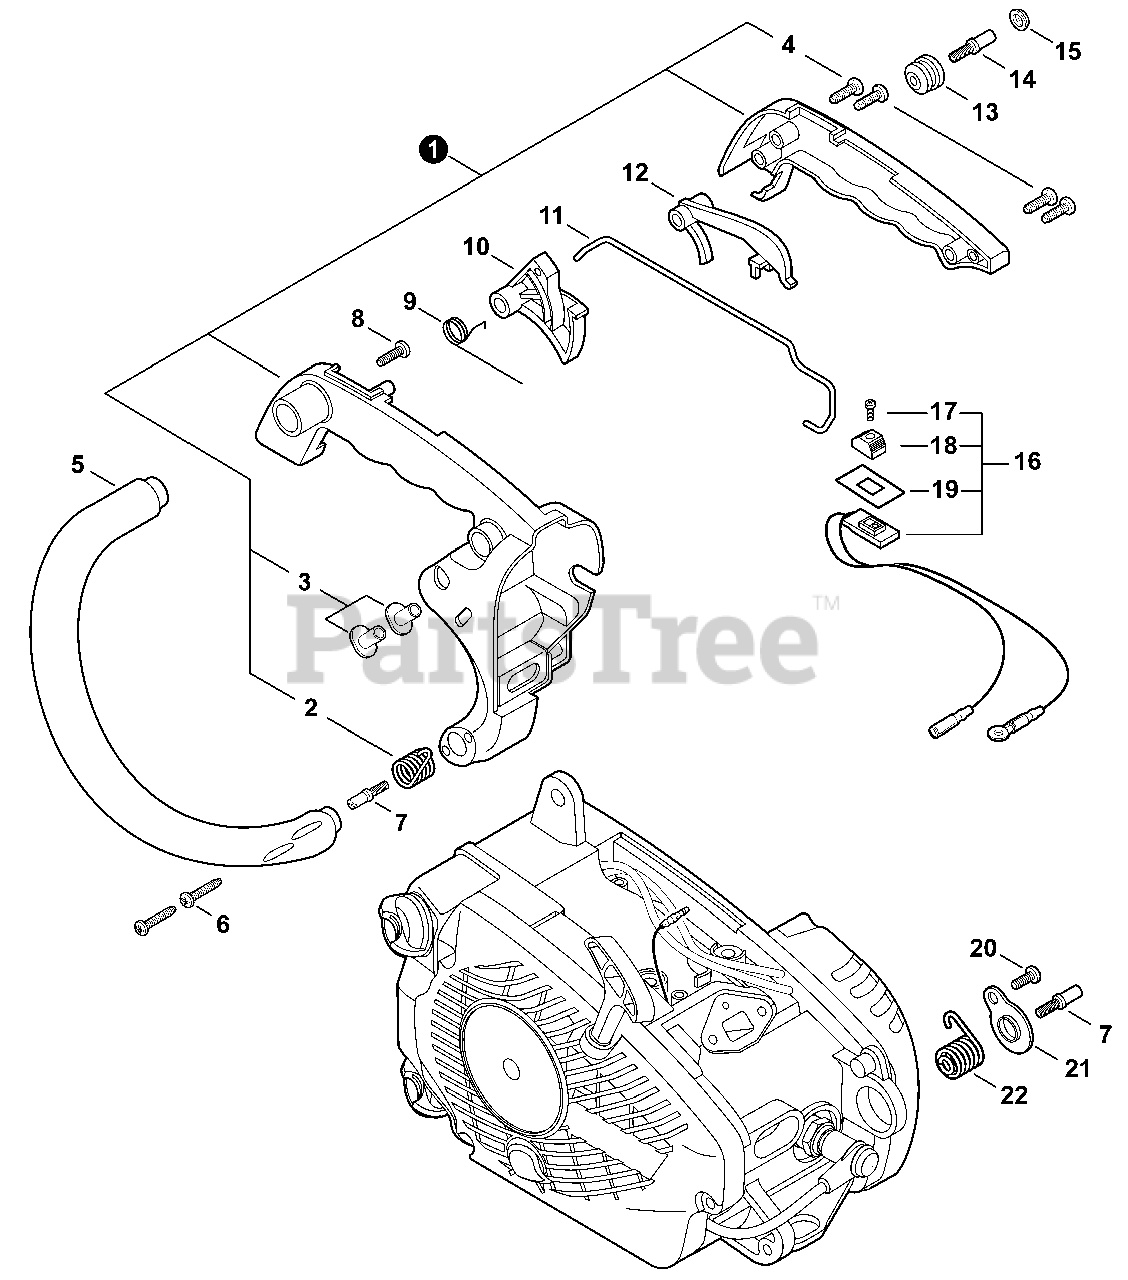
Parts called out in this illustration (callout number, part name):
1	HANDLE SET, REAR
2	SPRING, COMPRESSION
4	SCREW 4×16
5	HANDLE, FRONT
6	SCREW 4×16
7	BOLT 4×12
8	SCREW 5×20
9	SPRING, TORSION
10	TRIGGER, THROTTLE
11	ROD, THROTTLE
12	LOCKOUT, THROTTLE
13	CUSHION 4
14	BOLT 4×15
15	CAP, CUSHION
16	SWITCH, ON-OFF
17	SCREW 3×10
18	KNOB, SWITCH - ORANGE
19	LABEL, SWITCH
20	SCREW 4×12
21	PLATE, EYE
22	SPRING, COMPRESSION
